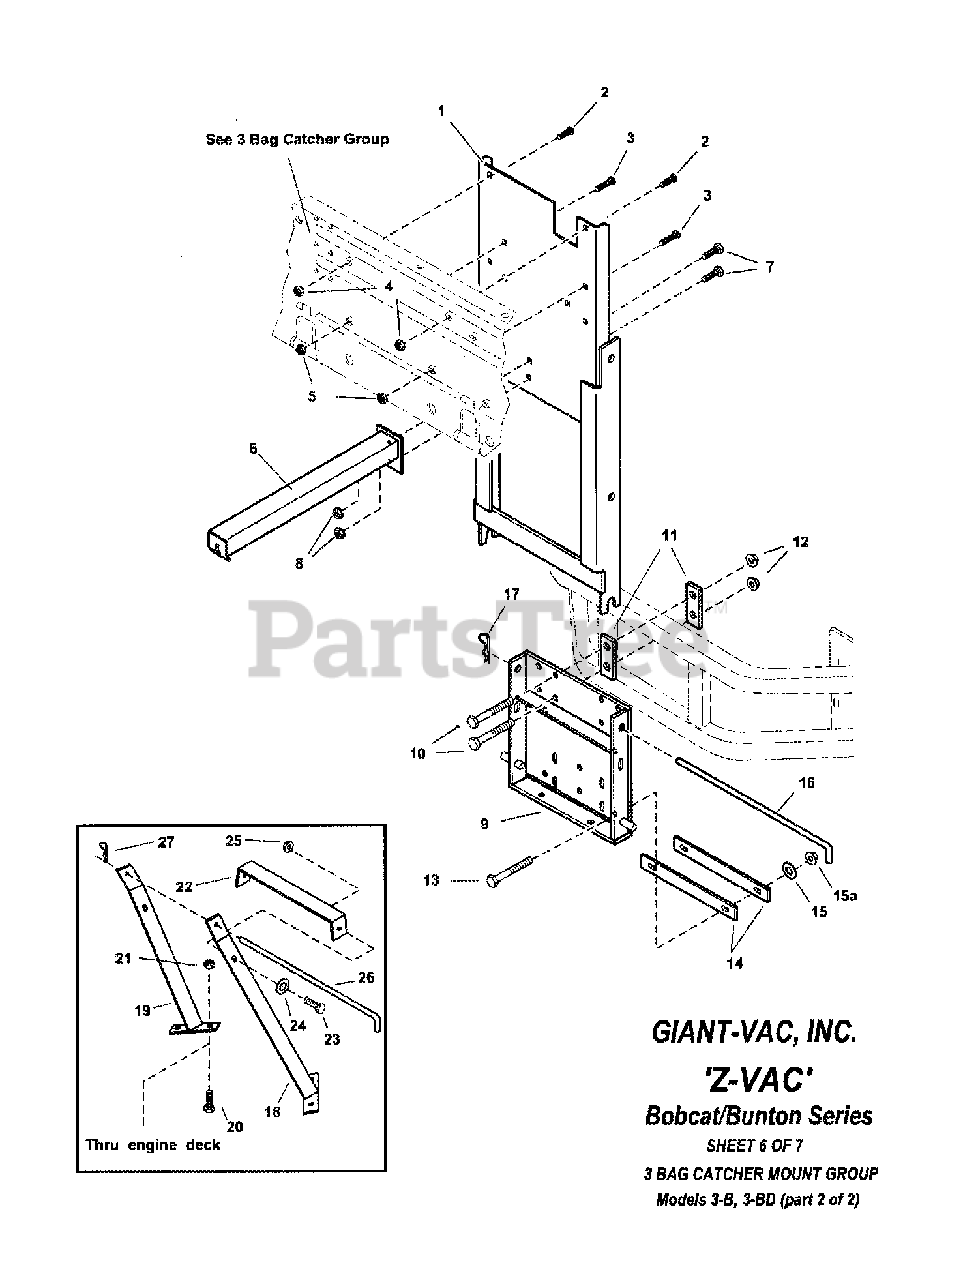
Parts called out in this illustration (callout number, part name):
1	WELDMENT, Catcher Support
2	BOLT, 5/16-18 x 3/4" Square Neck Carriage, GR5
3	BOLT, 5/16-18 x 1-1/4" Square Neck Carriage
4	NUT, 5/16-18 Hex Flange Lock
5	NUT, 5/16-18 Hex Flange Lock
6	WELDMENT, Cover Latch Arm
7	BOLT, 5/16-18 x 3/4" Square Neck Carriage, GR5
8	NUT, 5/16-18 Hex Flange Lock
9	WELDMENT, Bumper Mount Plate
10	SCREW, 3/8-16 x 2-1/2" Hex Head Cap, GR5
11	BAR, Clamp
12	NUT, 3/8-16 Hex Flange Lock
13	SCREW, 3/8-16 x 1-3/4" Hex Head Cap, GR5
14	REINFORCEMENT, Bumper
15	WASHER, 3/8" Flat
16	HITCH ROD
17	HAIRPIN, Clip
18	BAGGER BRACE, RH Side, Model 3-B
18	BAGGER BRACE, LH Side, Model 3-BD
19	BAGGER BRACE, LH Side, Model 3-B
19	BAGGER BRACE, LH Side, Model 3-BD
20	BOLT, 5/16-18 x 3/4" Square Neck Carriage, GR5
21	NUT, 5/16-18 Hex Flange Lock
22	BAGGER BRACE, Center
23	SCREW, 3/8-16 x 1-1/4" Hex Head Cap, GR5
24	WASHER, 3/8" Flat
25	NUT, 3/8-16 Hex Flange Lock
26	PIN, Bagger Brace Locking
27	HAIRPIN, Cotter
